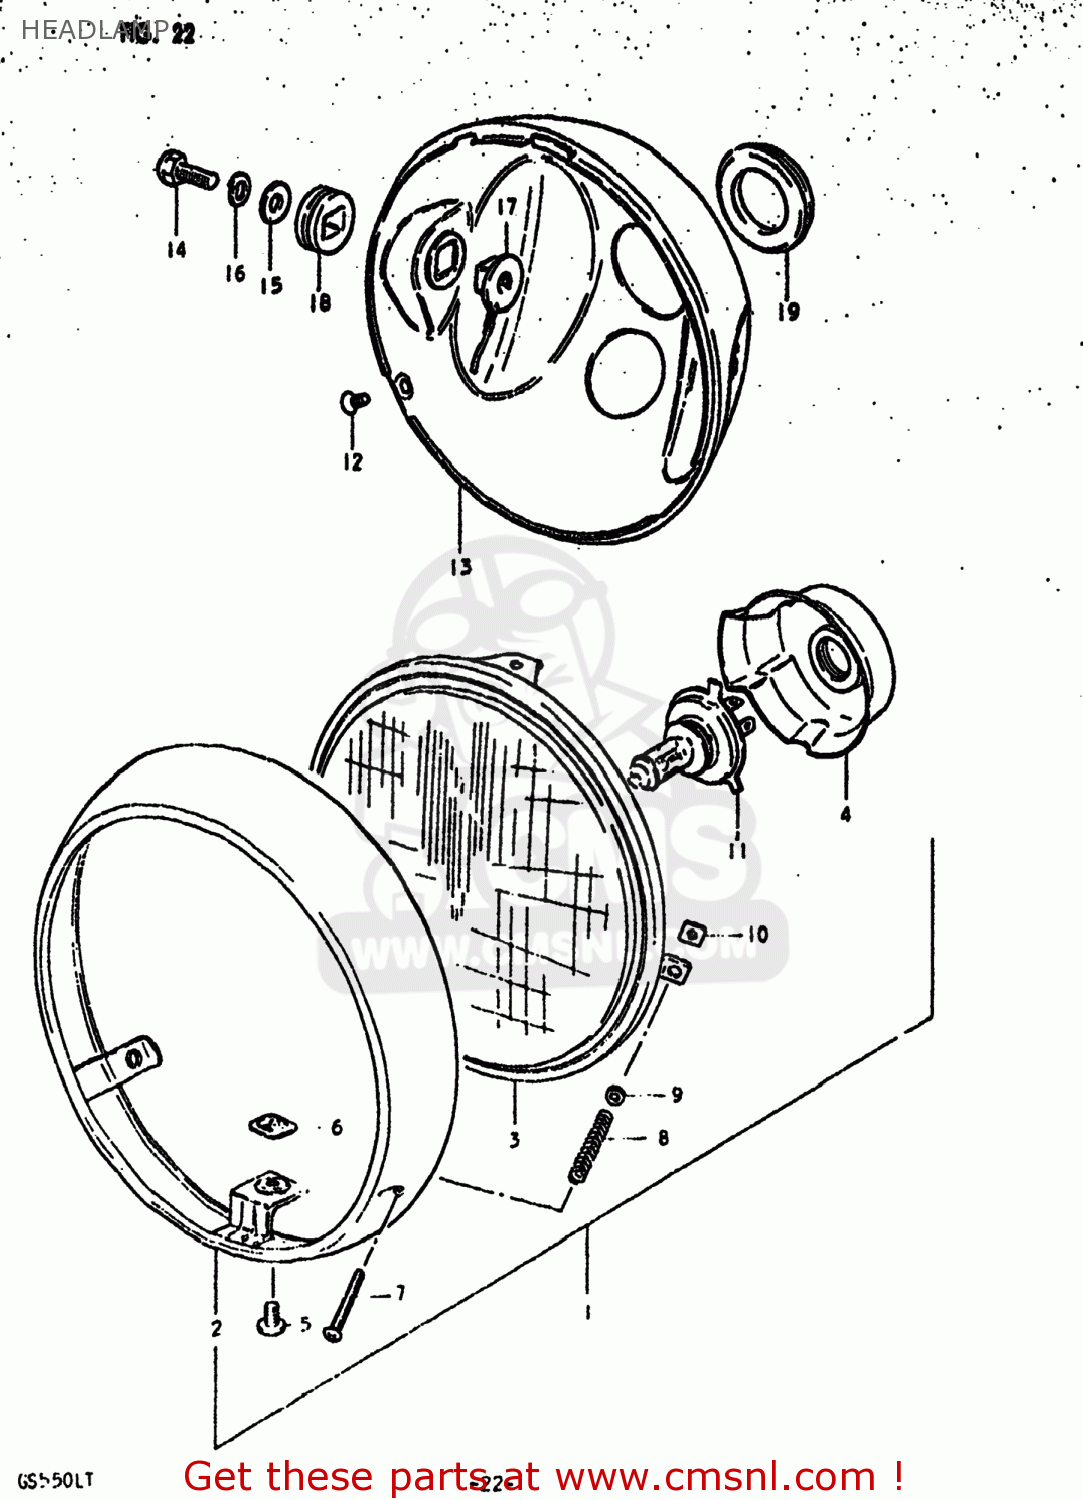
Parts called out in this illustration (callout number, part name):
1	HEADLAMP ASSEMBLY
2	RIM,HEADLAMP
3	LAMP UNIT
4	COVER,HEADLAMP SOCKET
5	SCREW
6	NUT
7	SCREW,HEADLAMP ADJUST
8	SPRING,HEADLAMP ADJUST
9	WASHER
10	WASHER
11	BULB(12V60/55W,H4)
12	SCREW
13	HOUSING,HEADLAMP
14	BOLT
15	WASHER
16	LOCK WASHER
17	SPACER,HEADLAMP HOUSING
18	CUSHION,HEADLAMP HOUSING
19	GROMMET,HEADLAMP HOUSING
